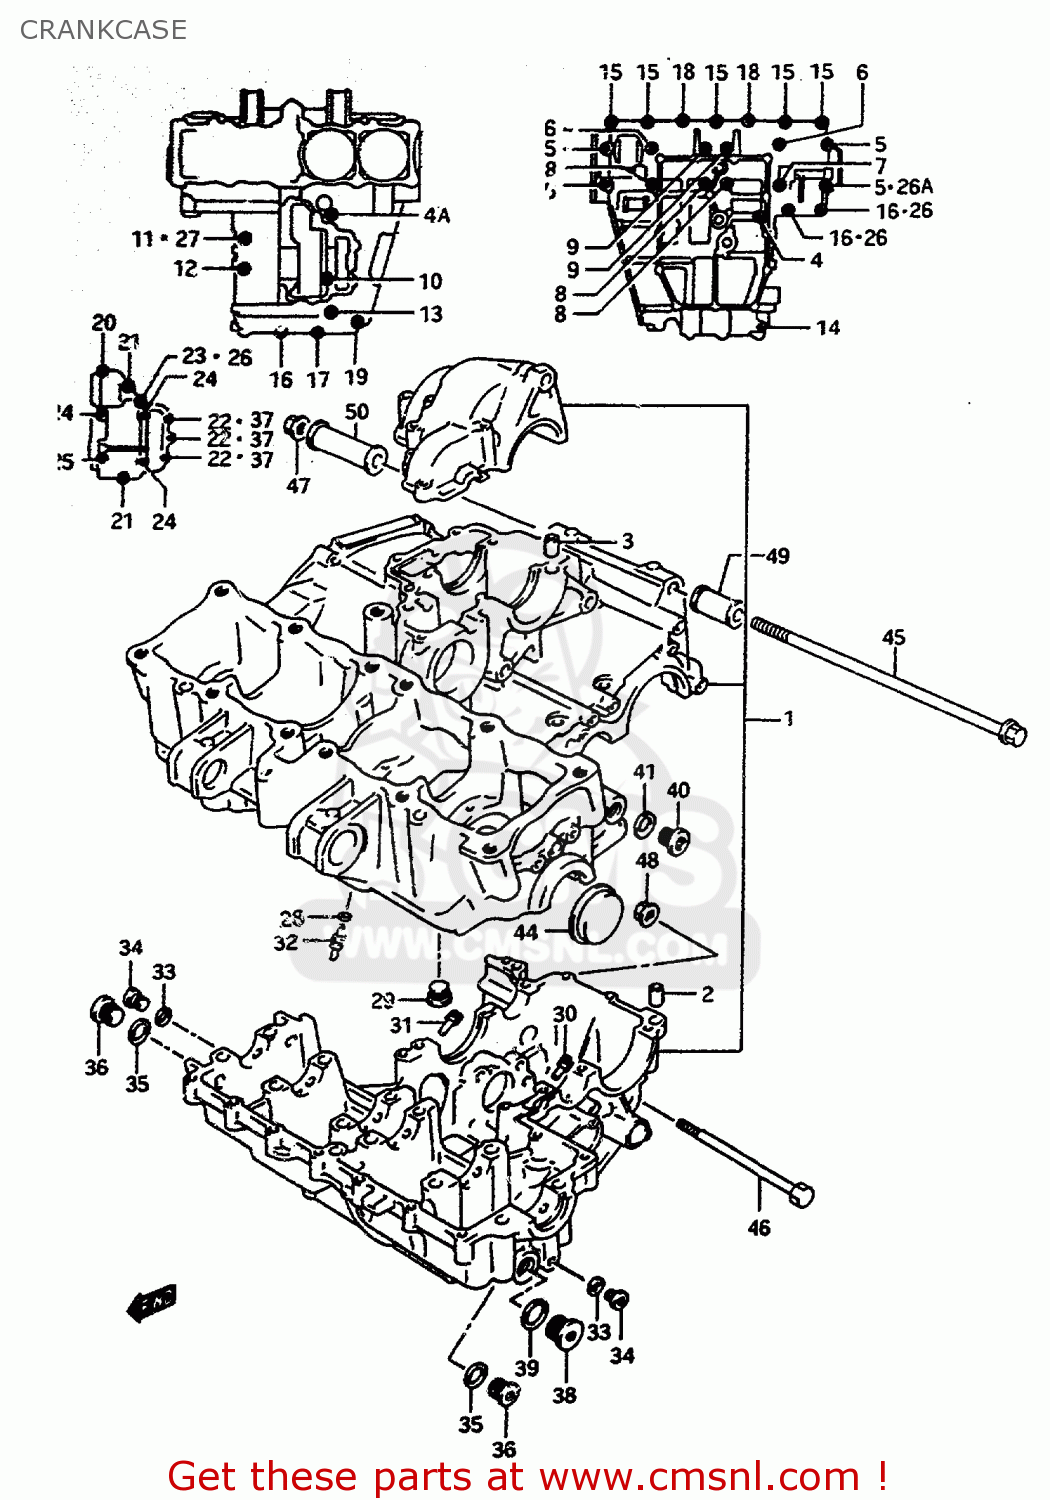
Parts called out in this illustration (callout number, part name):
1	CRANKCASE SET
2	PIN(10.4X13X22)
3	PIN
4	BOLT(6X105)
4A	BOLT(6X105)
5	BOLT 9X80
6	BOLT(9X95)
7	BOLT(9X105)
8	BOLT(9X115)
9	BOLT(9X60)
10	BOLT
11	BOLT
12	BOLT
13	BOLT
14	BOLT
15	BOLT
16	BOLT
17	BOLT
18	BOLT
19	BOLT
20	BOLT
21	BOLT
22	BOLT
23	BOLT(6X145)
24	BOLT
25	BOLT
26	GASKET(6.2X13X1.2) (NAS)
26A	GASKET(10.2X20X2).3 (NAS)
27	GASKET(8.2X14X1) (NAS)
28	O RING(D:1.2,ID:4)
29	PLUG,CRANKCASE,UPPER
30	JET
31	JET(140)
32	JET(13)
33	GASKET(10X14X3.6) (NAS)
34	PLUG(10X6.8)
35	GASKET(16X22X2) (NAS)
36	PLUG
37	GASKET(5.8X11X1.2) (NAS)
38	PLUG(22X11)
39	GASKET(22X27X2) (NAS)
40	PLUG
41	GASKET(13.8X18.8X4.8) (NAS)
42	BEARING,CRANK THRUST(GREEN)
43	BEARING,CRANK THRUST(RED)
44	PLUG
45	BOLT 10X280
46	BOLT(12X140)
47	NUT
48	NUT 12MM
49	SPACER,ENG MTG RR UPR,L(L45)
50	SPACER,ENGINE MOUNT
